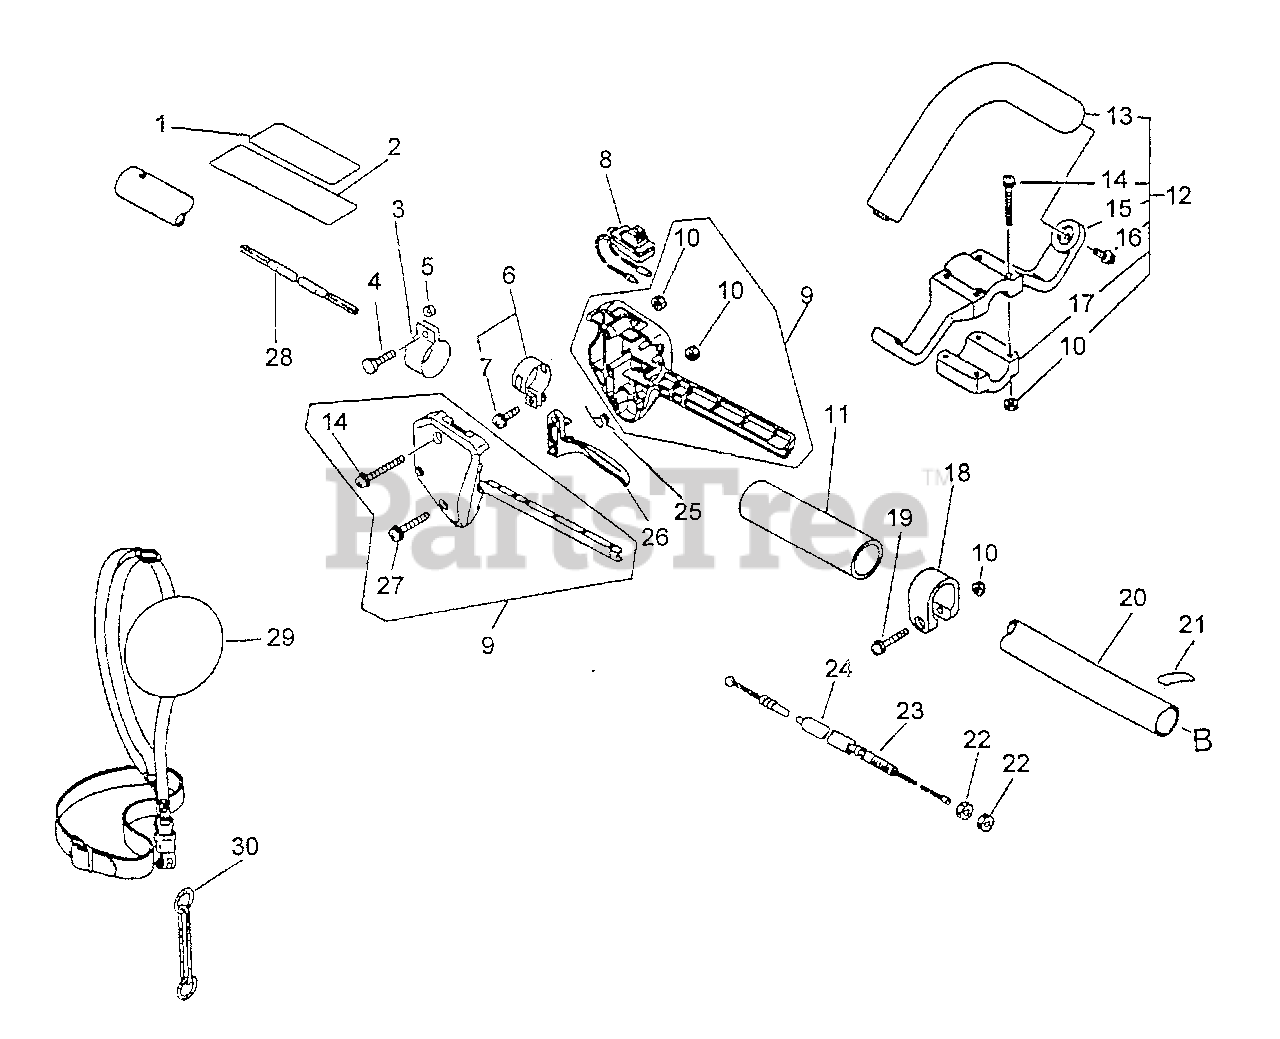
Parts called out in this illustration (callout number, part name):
1	LABEL, CAUTION
2	LABEL, CAUTION
4	BOLT 5×18
5	SPACER, GUARD
6	HANGER ASSY
7	SCREW 5×12
8	SWITCH, ON-OFF
9	BRACKET, THROTTLE
10	NUT M5
12	HANDLE ASSY
13	HANDLE
14	SCREW 5×35
15	BRACKET, HANDLE
16	SCREW 5×14
17	BRACKET, HANDLE
19	SCREW 5×30
20	PIPE, MAIN
21	LABEL - ALIGNMENT
23	CABLE, THROTTLE
24	TUBE - VINYL
25	SPRING, TORSION
26	TRIGGER, THROTTLE
27	SCREW 5×25
28	DRIVESHAFT
29	SHOULDER STRAP ASSY
30	HOOK
